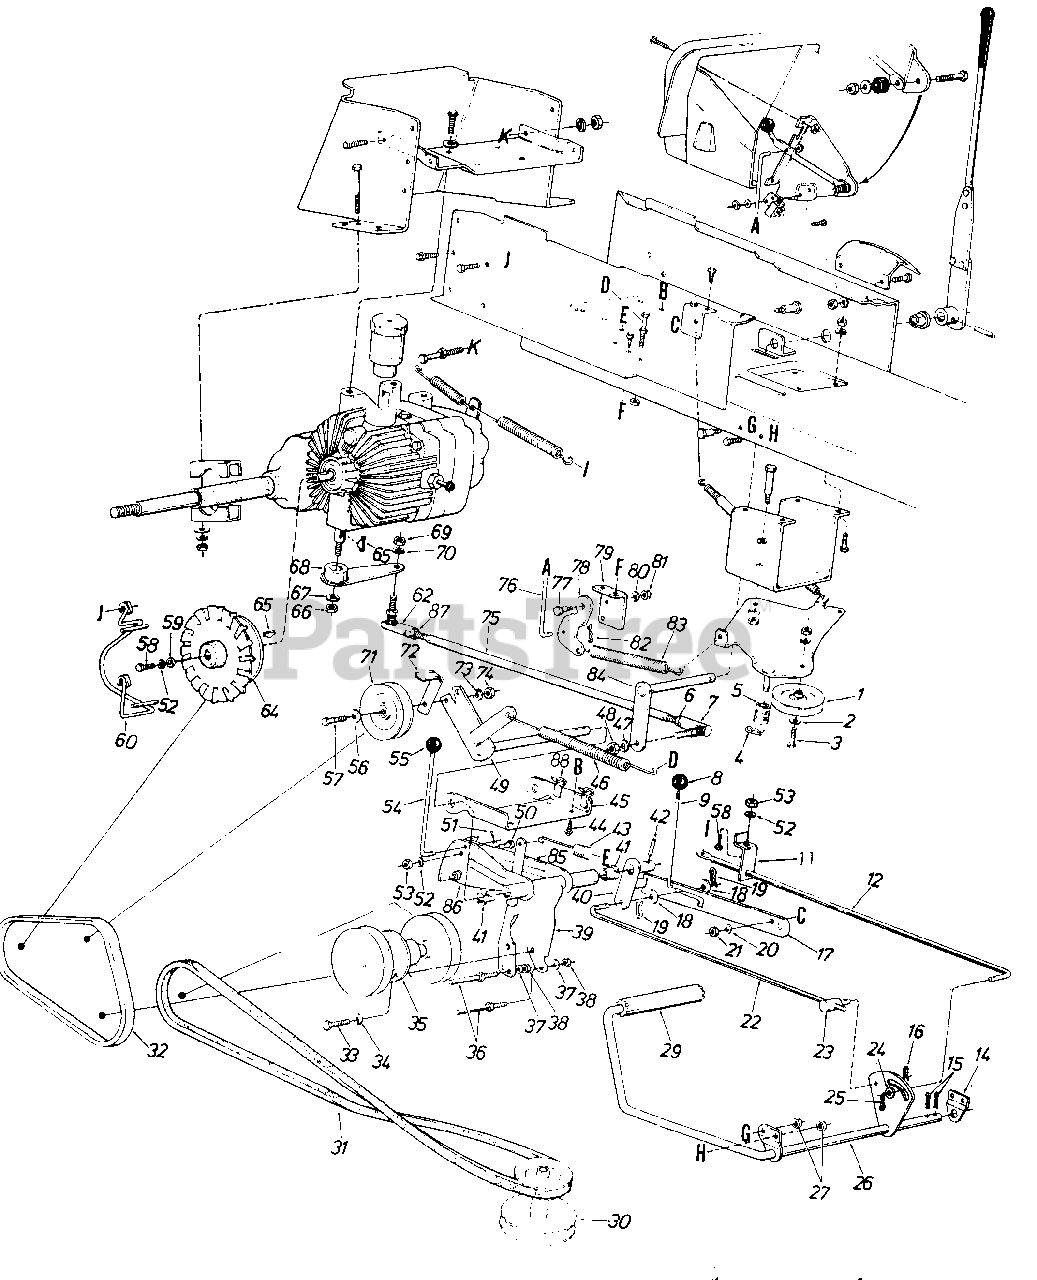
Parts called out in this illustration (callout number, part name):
1	4" Dia. "V"-Idler Pulley
2	Fl-Wash. 3/8" I.D.
3	Hex 801t 3/8-16 x 1.25" Lg.
4	Intern. Cotter Pin 5/16" Dia.
5	Spacer
6	Hex Jam L-Nut 3/8-24 Thd.
7	Ball Joint Ass'y. 3/8-24 Thd.
8	Ball Knob
9	Parking Brake Link
11	Brake Rod Hanger
12	Brake Rod
14	Clutch Rod Brg. Brkt.
15	Cotter Pin 118" Dia. x 1.00" Lg.
16	Hairpin Cotter 1/2" Dia.
17	Parking Brake Cam
18	Fl-Wash. .406 I.D. x 1.00" O.D. x .030
19	Hairpin Cotter 1/2" Dia.
20	L-Wash. 5/16" I.D.
21	Hex Nut 5/16-18 Thd.
22	Brake Cam Rod
23	Pivot Bushing
24	Fl-Wash. .401" I.D. x .749" O.D. x .057" Thk.
25	Cotter Pin 3/32" Dia. x .75" Lg.
26	Clutch Brake Pedal Ass'y.
27	Hex L-Nut 3/8-16 Thd.
29	Foot Pad
30	Two-Step Engine Pulley 4.75" and 5.56"
31	"V"-Belt 1/2" x 59" Lg.
32	"V"-Belt 1/2" x 37" Lg.
33	Hex Sems Bolt 5/16-18 x .75" Lg.*
34	L-Wash. 5/16" I.D.
35	Jack Shaft Ass'y.
36	Stud 3/8-16 x 3.62" Lg.
37	L-Wash. 3/8" I.D.*
38	Hex Nut 3/8-16 Thd.*
39	Jack Shaft Mtg. Brkt. Ass'y.
40	Clutch Idler Horn Ass'y.
41	Nyliner 5/8" I.D. x .88" Lg.
42	Spring Pin Spiral 1/4" Dia. x 1.5" Lg.
43	Ext. Spring
44	Hex Wash. Hd. Self-Tap Scr. 1/4-20 x .50" Lg
45	Idler Mtg. Brkt.
46	Ext. Spring
47	L-Wash. 3/8" I.D.
48	Hex Nut 3/8-24 Thd.
49	Clutch Brkt. Ass'y.
50	Hex Bolt 1/4-20 x .50" Lg.
51	Internal Cotter Pin 5/16" Dia. Rod
52	L-Wash. 1/4" I.D.*
53	Hex Nut 1/4-20 Thd.*
54	Relief Valve Lockout Rod
55	Ball Knob
56	Fl-Wash. 3/8" I.D.
57	Hex Bolt 3/8-16 x 1.25" Lg.
58	Hex Bolt 1/4-20 x .62" Lg.s
59	Fl-Washer
60	Belt Guard Ass'y.
62	Ball Joint Ass'y. 3/8-24 L.H. Thd.
64	Transaxle Pulley w/Fan
65	Hi-Pro Key 118" x 1/2" Dia.
66	Hex Nut 3/8-16 Thd.
67	L-Wash. 3/8" I.D.
68	Pintle Arm Ass'y.
69	Hex Nut 3/8-24 Thd.
70	L-Wash. 3/8" I.D.*
71	4" "V"-Idler Pulley
74	Hex Nut 3/8-16 Thd.*
75	Speed Control Rod
76	Deck Control Rod
77	Shld. Scr. .437" Dia. x .162" Lg. (5/16-18)
78	Deck Control Pivot Brkt.
79	Parking Brake Cam Mtg. Brkt.
80	L-Wash. 5/16" I.D.
81	Hex Nut 5/16-18 Thd.*
82	Internal Cotter Pin 5/16" Rod
83	Extension Spring
84	Speed Control Shaft Ass'y.
85	Relief Valve Cam-L.H.
86	Relief Valve Cam-R.H.
87	Hex Jam L-Nut 3/8-24 L.H. Thd.*
88	Plastic Hose Clamp
